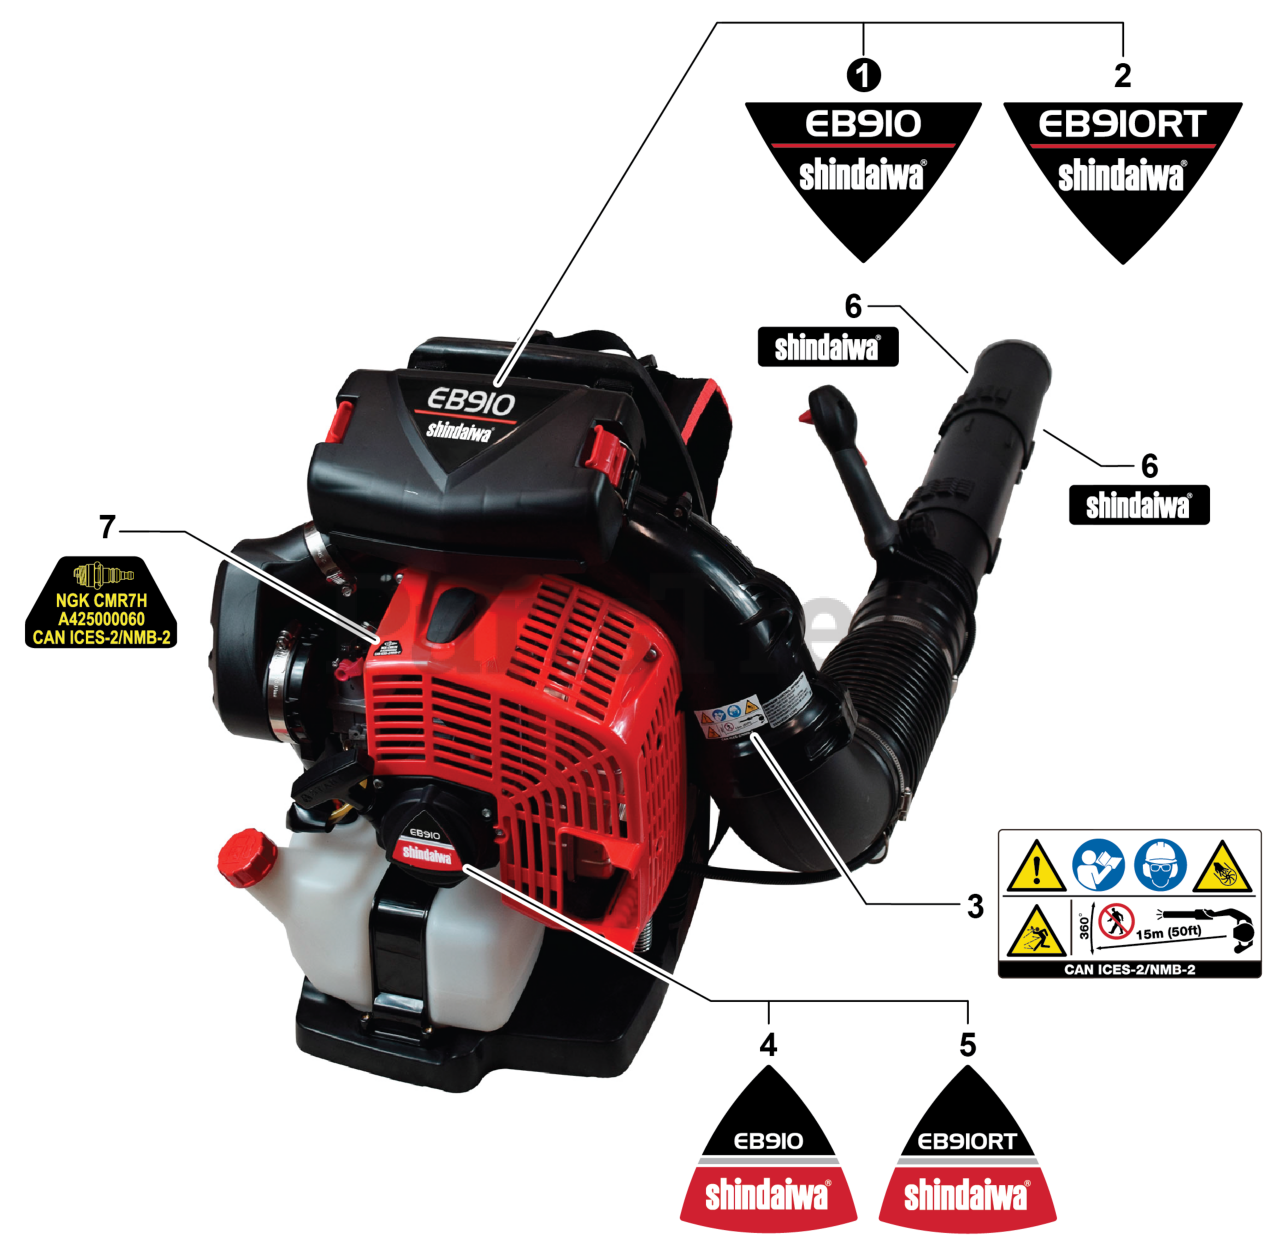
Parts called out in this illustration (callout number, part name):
1	LABEL - EB910
2	LABEL - EB910RT
3	LABEL - CAUTION
4	LABEL - EB910
5	LABEL - EB910RT
6	LABEL - SHINDAIWA BLOWER TUBE
7	LABEL - SPARK PLUG - CMR7H
